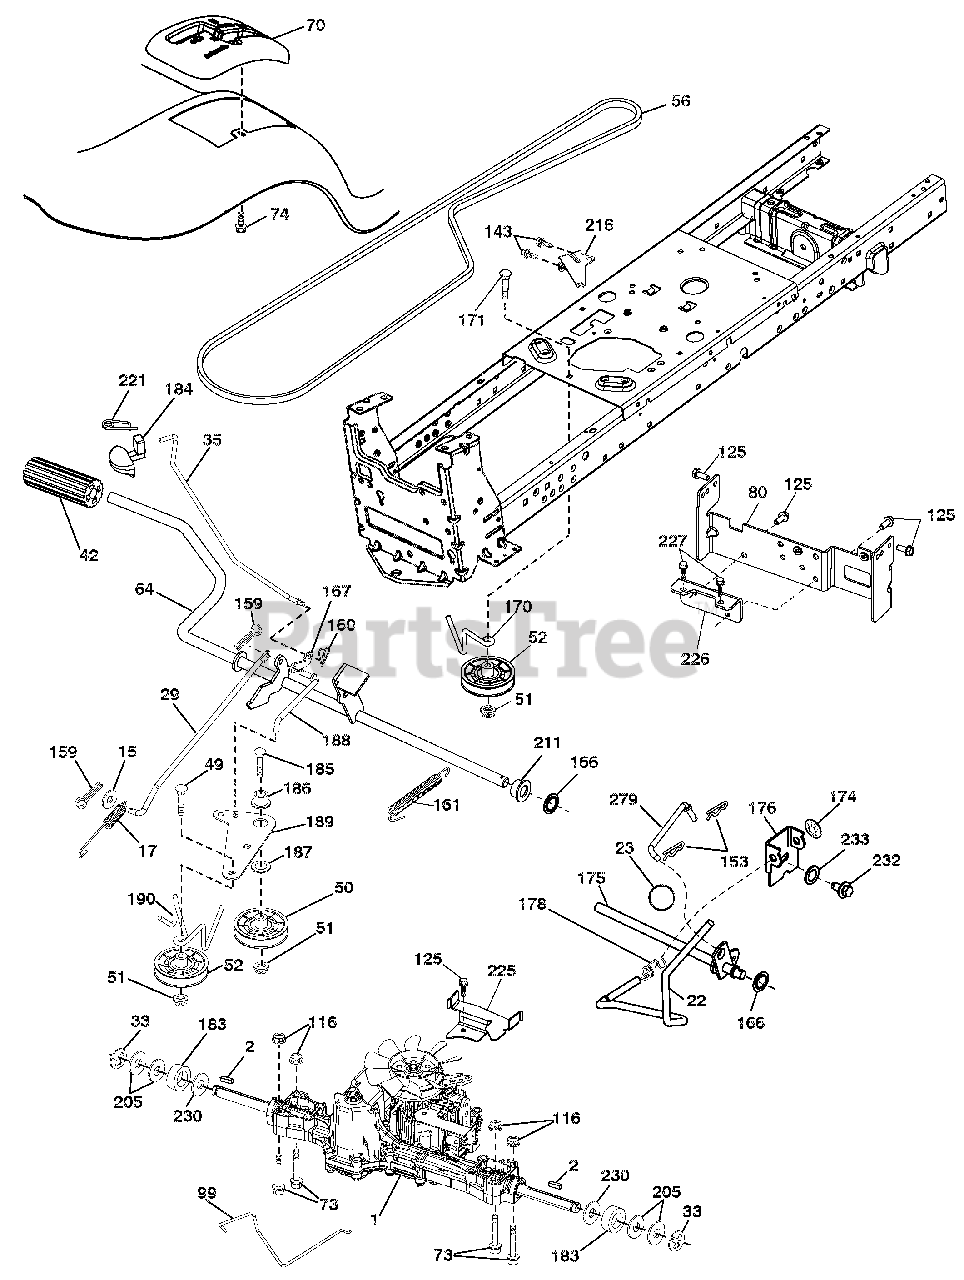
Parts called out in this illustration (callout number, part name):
1	TRANSAXLE, TUFFTORQ K46 BA(408214) (ORDER PARTS FROM TRANSAXLE MANUFACTURER)
2	KEY.SQUARE.2.0 X .1845/.1865
15	WASHER.13/32 X 13/16 X 16 GA.
17	SPRING.BRAKE.K46.GREEN
22	ROD.SHIFT.FENDER.TLT.2006
23	KNOB DELUXE
29	ROD.BRAKE.K46
33	E-RING.#5133-75
35	ROD, BRAKE, PARK
42	COVER PEDAL BLK ROUND
49	BOLT.RDHD.3/8-16UNCX1-3/4.GR5
50	IDLER.FLAT.910"OFFSET
51	Nut, Hex, Flangelock 3/8-16
52	IDLER.V-GROOVE.910"OFFSET
56	V-BELT.MOWER.92.40.42/K46
64	SHAFT ASM.PEDAL.BRAKE CONTROL
70	CONSOLE SHIFT STL HYD BLACK TX
73	BOLT 5/16-18 X 2 1/2 G.5
74	SCREW.HEX.WSH.HI-LO.1/4X1/2UNC
80	STRAP.TORQUE.K46/18"TEX
99	ROD.SPRING.BYPASS.K46.LT.Z
116	Nut, Lock Hex Flange 5/16-18 u
125	SCREW.5/16-18X3/4.SMGML.TAP/BL
143	SCREW.THDROL.5/16-18 X 1/2TYTT
153	RETAINER SPRING
159	PIN.COTTER.1/8 X 3/4.CAD.
160	RETAINER.CLIP(M).DIA.290
161	SPRING.RETURN.CLUTCH.6.75
166	NUT PUSH .625
167	LATCH.BRAKE.PARKING
170	KEEPER BELT CENTERSPAN
171	BOLT.RD.HD.SQ.NK.3/8-16UNC X 2
174	NUT.PUSH..500
175	SHAFT ARM SHIFT
176	ARM.CLEVIS.ROD.SHIFT
178	SPRING.SHIFT.GT.2006
183	SPACER.AXLE.HYDRO/PEERLES
184	HANDLE PARKING BRAKE
185	BOLT.RDHD.3/8-16UNC X2-3/4 GR5
186	SPACER.RETAINER
187	WASHER.13/32 X 2 X 10 GA.
188	LINK.CLUTCH.GROUND DRIVE
189	BELLCRANK.GROUNDRIVE.NSTG/NSTL
190	KEEPER.BELLCRANK.DRIVE.GROUND
205	WASHER.25/32 X 1-5/8 X 16GA.
211	BUSHING.SHAFT.BRAKE.HAND CONTR
216	BRACKET.PULLEY.IDLER.WTEX
221	RETAINER.SPRING.CLIP.HANDLE
225	KEEPER.BELT.TRANSAXLE.K46
226	BRACKET.MOUNT.TORQUE.K46.TLT
227	SCREW 5/16-18 X 3/4
230	WASHER.HARDEN..793 X 1.637X060
232	BOLT.FIN HEX.7/16-14X1 GR5
233	WASHER.SERRATED
279	LINK SHIFT T/A
